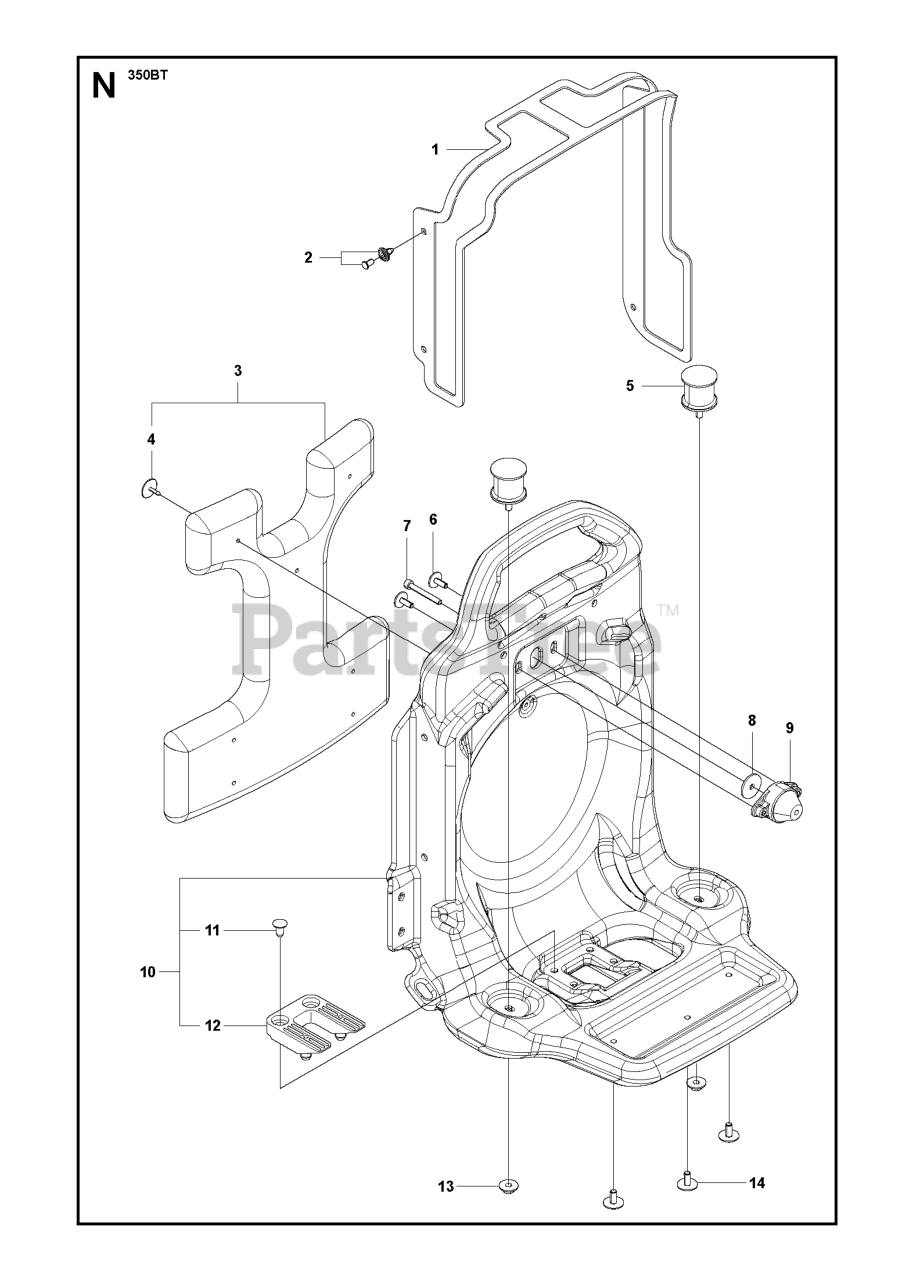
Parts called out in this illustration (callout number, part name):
2	CLIP
3	PAD COMP
4	CLIP
5	DAMPER LOWER
8	WASHER
11	CLIP
